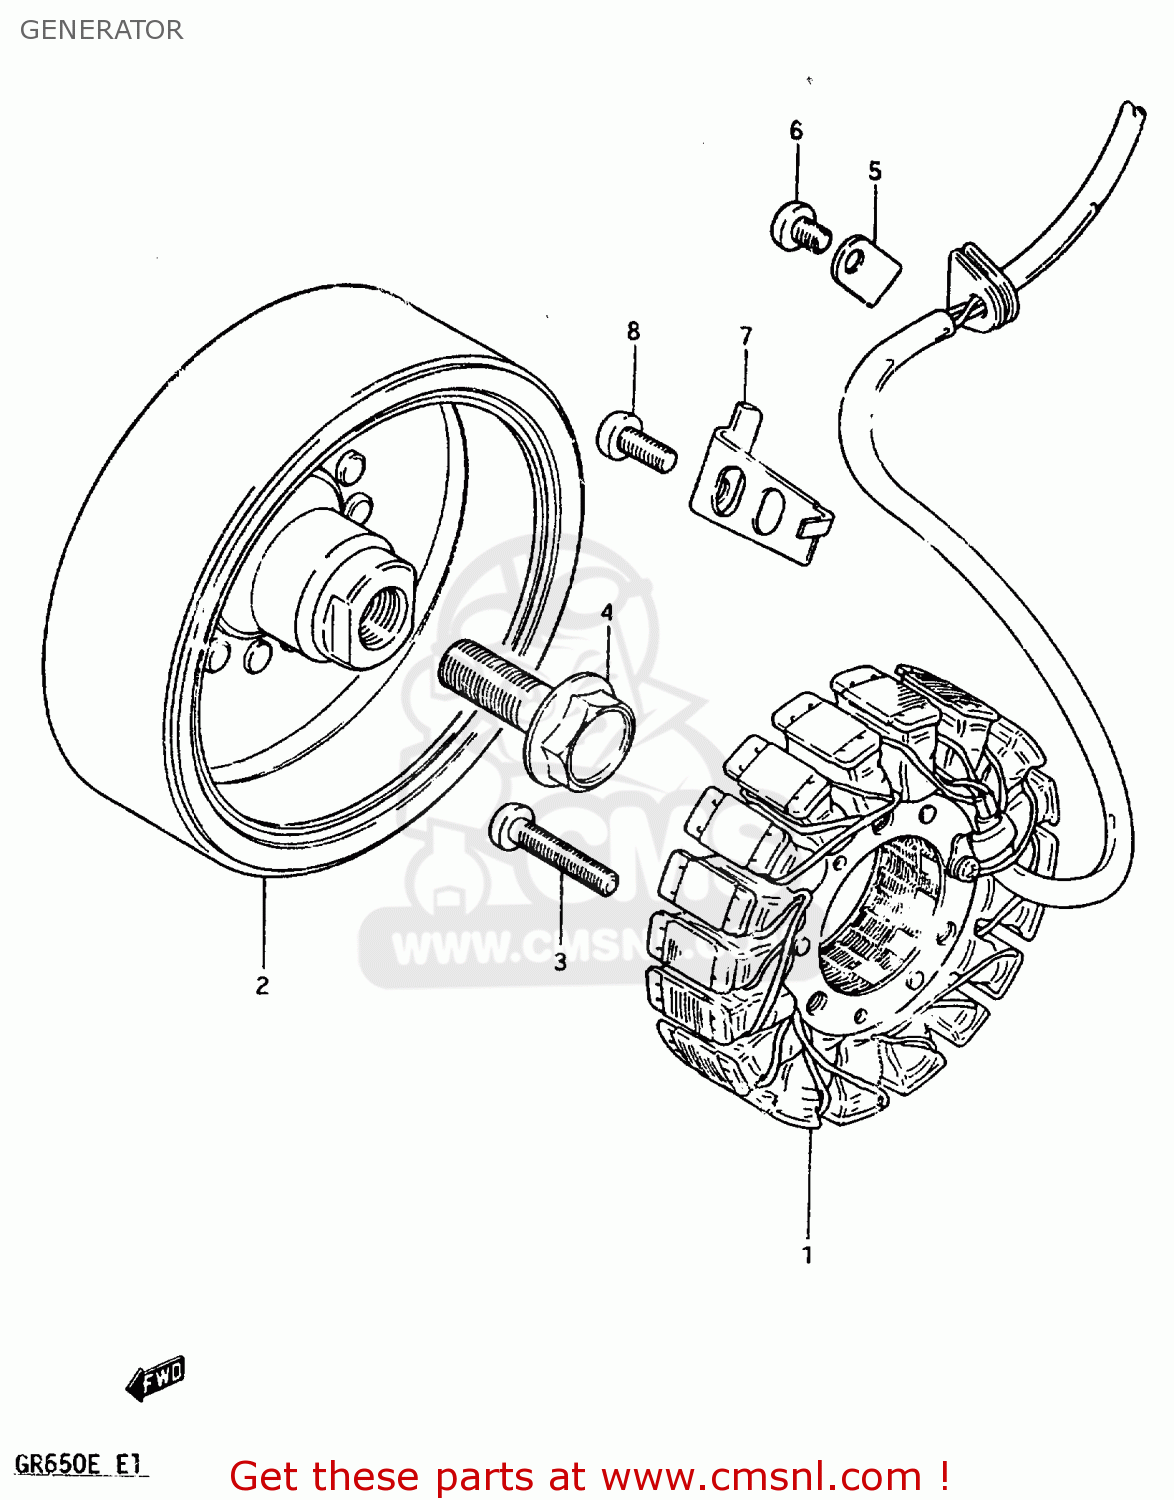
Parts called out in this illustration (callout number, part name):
1	STARTER ASSY
2	ROTOR
3	SCREW
4	BOLT(12X40)
5	CLAMP,GENERATOR LEAD WIRE
6	SCREW
7	CLAMP,GENERATOR LEAD WIRE
8	SCREW
